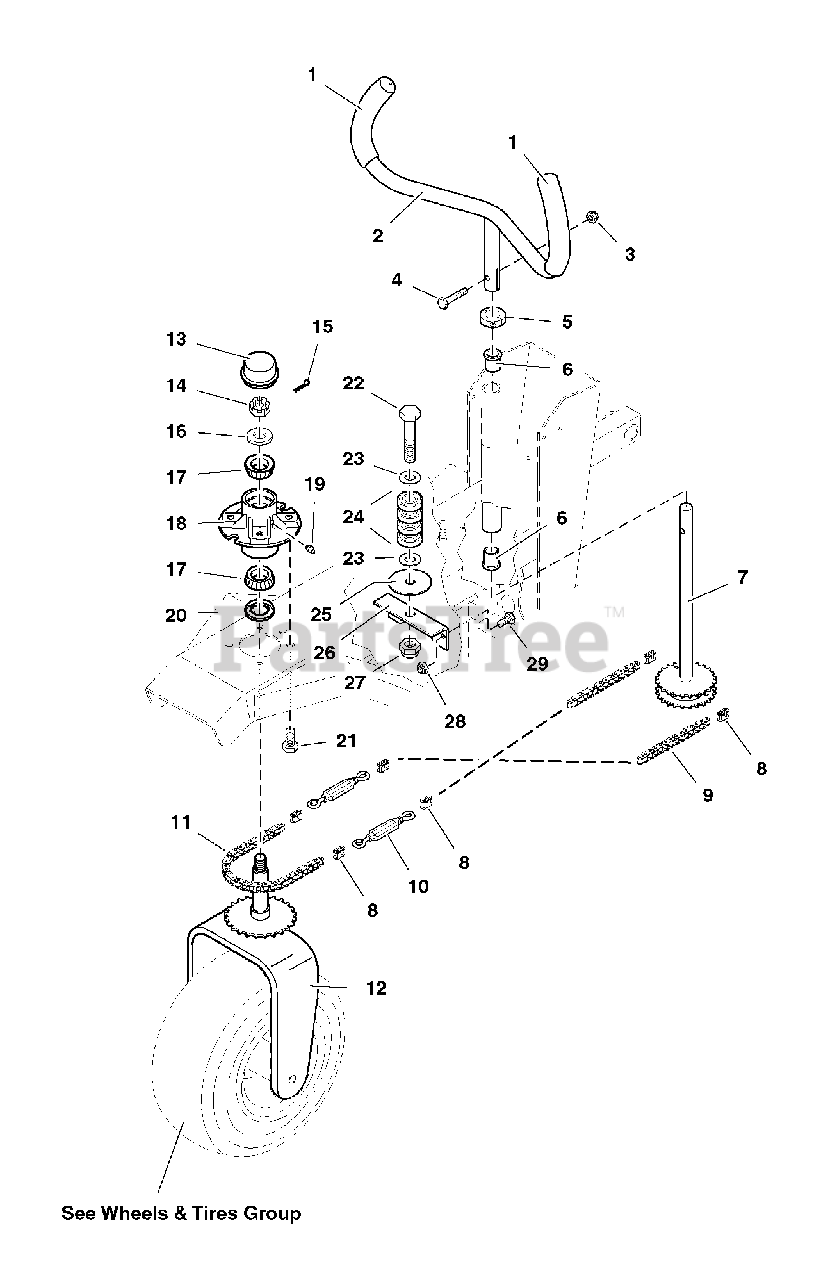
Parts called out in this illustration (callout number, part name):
2	STEERING HANDLE
3	NUT, Hex, Nylon Lock, 3/8-16
4	CAPSCREW, Hex Hd, 3/8-16 x 1-1/2
5	COLLAR, 1" Split
6	BUSHING, Flange
7	SHAFT, Steering Sprocket
8	LINK, Chain
9	CHAIN, Roller, 31 Links
10	TURNBUCKLE
11	CHAIN, Roller, 35 Links
12	STEERING TIRE YOKE
14	NUT, Hex, Slotted, 3/4-16
16	WASHER, 3/4
17	BEARING, Tapered Roller
18	HUB, Steering
19	GREASE FITTING
20	SEAL, Grease
21	CAPSCREW, Hex Hd, 1/2-20 x 1-1/4
22	CAPSCREW, Hex Hd, 5/8-11 x 3
23	WASHER, 5/8
24	BEARING
25	WASHER, Chain
26	MOUNT, Chain Roller
27	NUT, Hex, Nylon Lock, 5/8-11
28	NUT, Hex, Nylon Lock, 5/16-18
29	CAPSCREW, Hex Hd, 5/16-18 x 3/4
